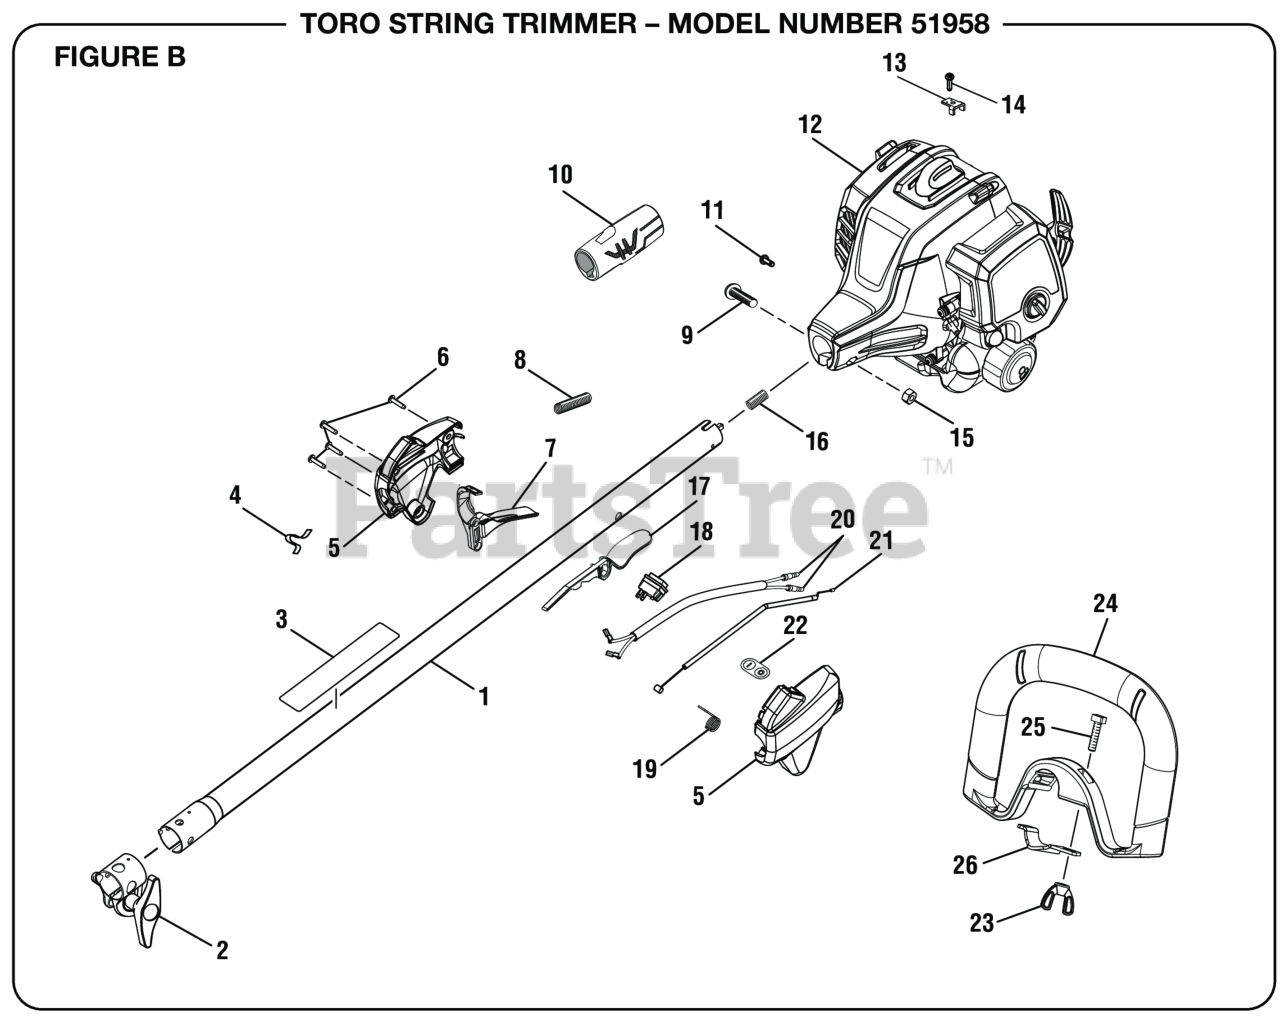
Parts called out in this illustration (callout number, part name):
1	Upper Boom Assembly
2	Boom Clamp Assembly
3	Warning Icon Label
4	Shoulder Strap Hook
5	Control Handle Assembly
6	Screw (M4 x 20 mm, T20 Torx Pan Hd. S.T.)
8	Corrugated Tube (225 mm)
9	Screw (M6 x 30 mm, T27 Torx Button Hd.)
10	Rear Handle Grip
11	Screw (M4 x 8 mm, T25 Torx Pan Hd. T.F.)
12	Powerhead Assembly
13	THROTTLE CABLE CLAMP
14	Screw (M4 x 16 mm, T20 Torx Pan Hd. S.T.)
15	Hex Nut (M6.3 x 1)
16	COMPRESSION SPRING
17	Trigger Lock
18	On/Stop Switch
19	Torsion Spring (Throttle Trigger)
20	Lead Assembly
21	Throttle Cable
22	On/Stop Label
23	Wing Nut (1/4-20, Plastic)
24	Front Handle w/Grip
25	Bolt (1/4-20 x 1 in., Square Hd.)
26	Front Handle Clamp
